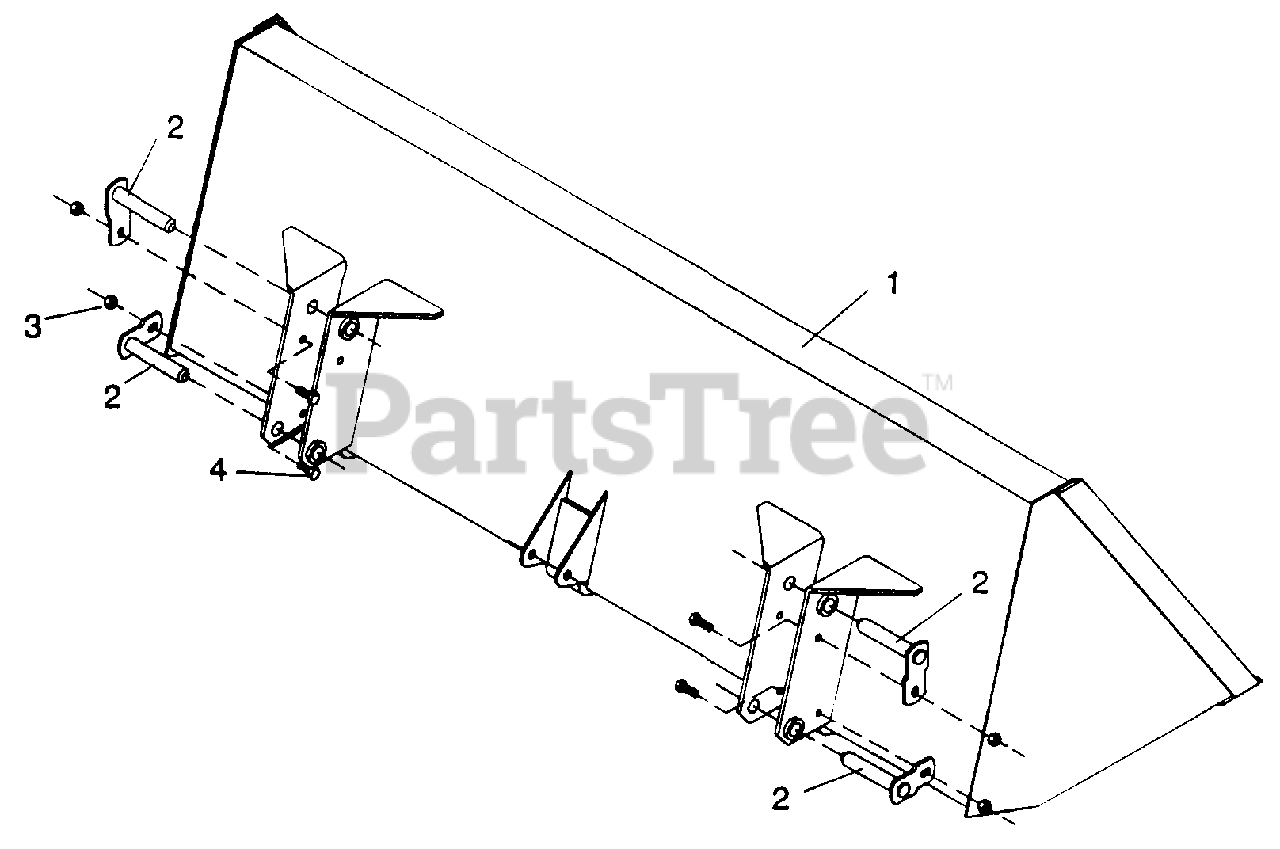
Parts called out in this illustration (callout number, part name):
1	48" Bucket
2	Bucket Pin
3	3/8 NC locknut
4	3/8 NC x 1 Carriage Bolt, GR5
